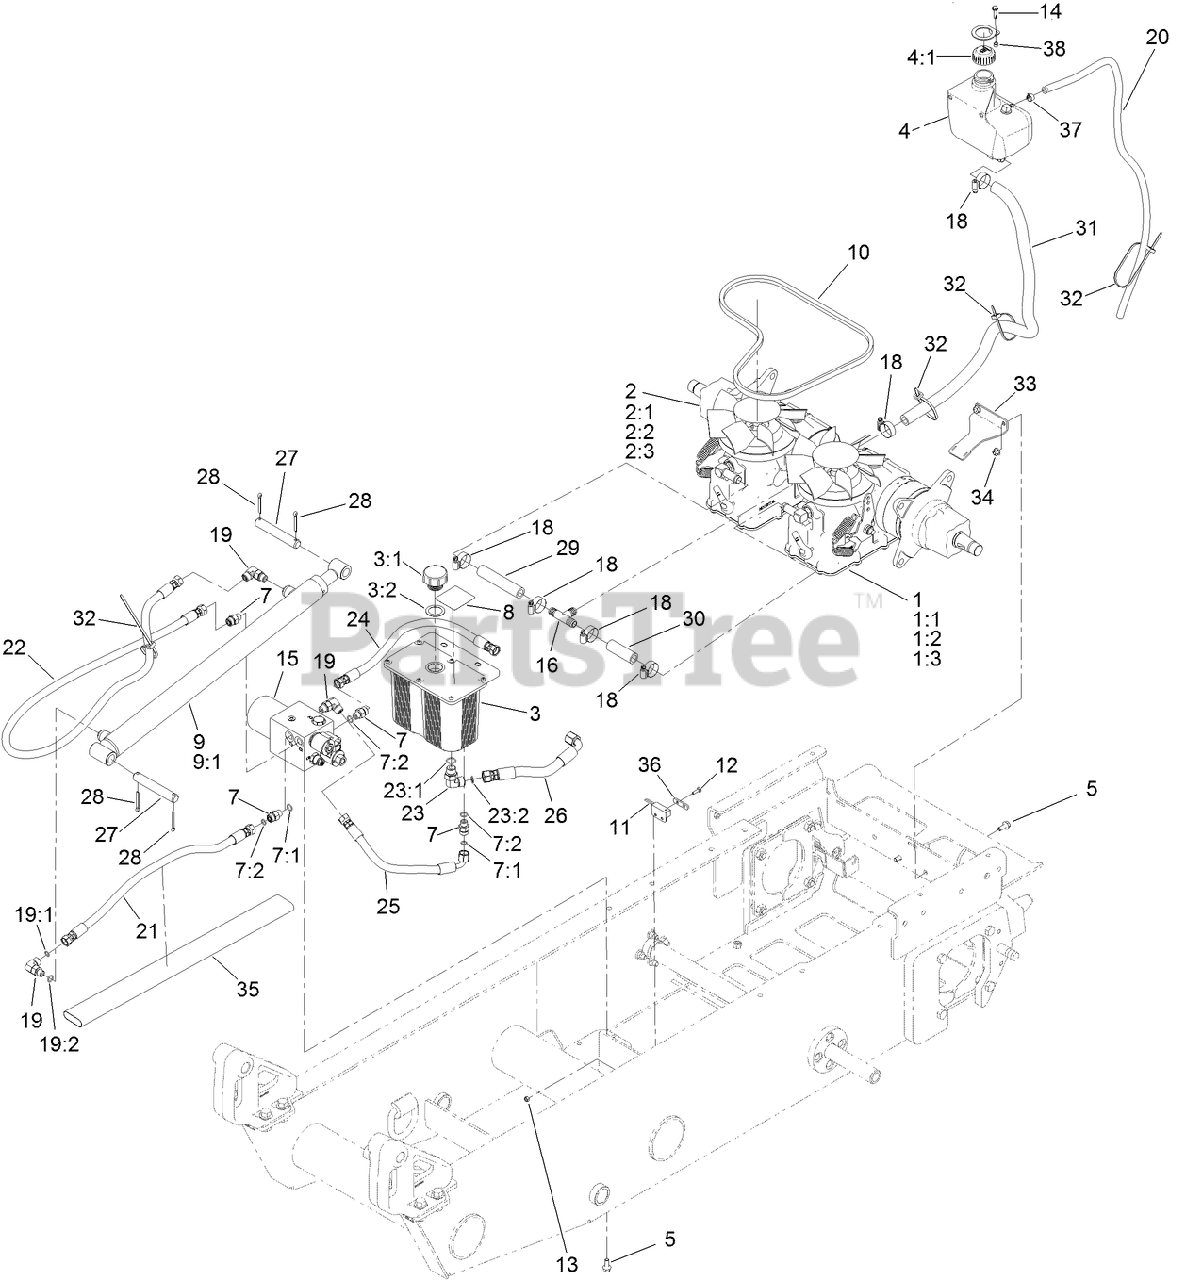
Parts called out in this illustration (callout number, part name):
1	LH HYDRO TRANSAXLE ASM
1:1	FILTER
1:2	PULLEY
1:3	FAN (8.3 INCH)
2	RH HYDRO TRANSAXLE ASM
2:1	FILTER
2:2	PULLEY
2:3	FAN (8.3 INCH)
3	TANK-HYDRAULIC
3:1	CAP-RESERVOIR, HYD
3:2	GASKET-CAP
4	TANK-HYD
4:1	CAP-VENTED
5	SCREW-HHF
7	FITTING-STRAIGHT
7:1	O-RING
7:2	O-RING
8	DECAL-WARNING
9	CYLINDER-HYDRAULIC
10	BELT
11	SWITCH-PROXIMITY
12	SCREW-CARR
13	NUT-LOCK, NI
14	SCREW-SELFDR
15	HYDRAULIC MANIFOLD ASM
18	CLAMP-HOSE
19	FITTING-ELBOW, 90 DEG
19:1	O-RING
19:2	O-RING
20	HOSE-BREATHER, TRANSMISSION
21	HOSE-HYDRAULIC
22	HOSE-HYDRAULIC
23	FITTING-ELBOW, 90 DEG
23:1	O-RING
23:2	O-RING
24	HOSE-HYDRAULIC
25	HOSE-HYDRAULIC
26	HOSE-HYDRAULIC
27	Pin-Pivot
28	PIN-COTTER
29	HOSE-HYD, HYDRO
30	HOSE-HYD, HYDRO
31	HOSE-HYD, HYDRO
32	TIE-CABLE
33	BRACKET-HOSE RETAINER
34	NUT-HF, NI
35	SLEEVE-PROTECTIVE
36	PLATE-SWITCH, PROXIMITY
37	CLAMP-HOSE
38	SPACER
